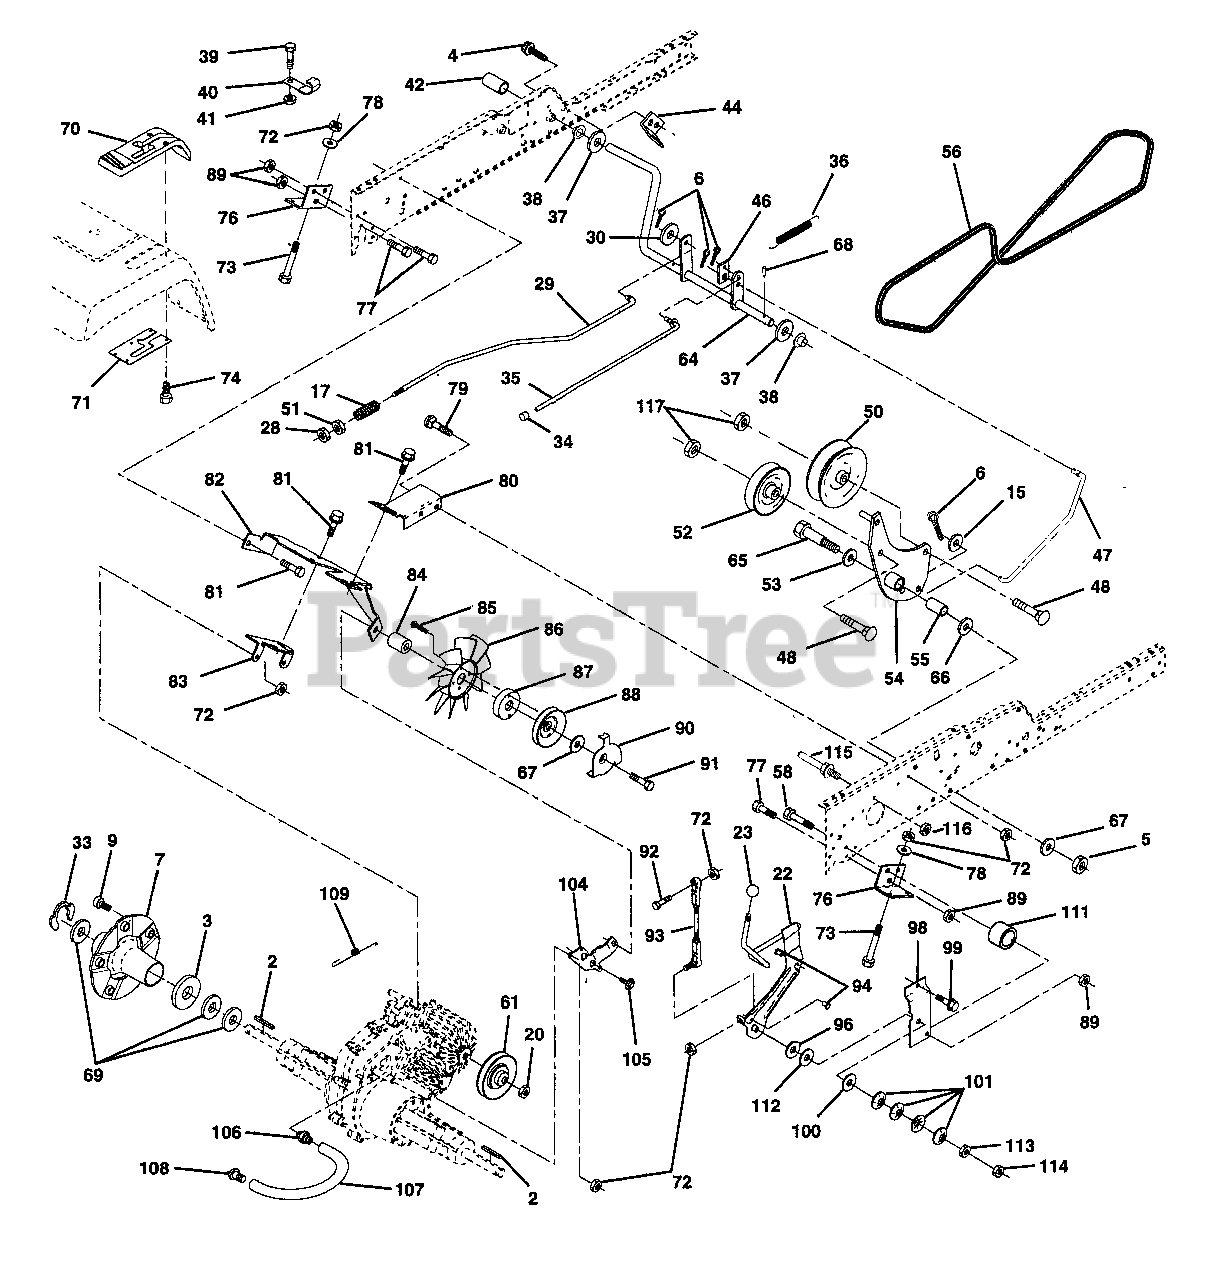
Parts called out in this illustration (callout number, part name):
2	Key 1 /4 x 2.5
3	Washer Thrust Axle Harden
4	Screw Thdrol 5/16-18 x 1/2
5	Nut Crownlock 3/8-16
6	Pin Cotter 1/8 x 3/4
7	Wheel Hub Asm.
15	Washer 13/32 x 13/16 x 16 Ga.
17	Spring Rod Brake
20	Nut Hex Jam Toplock 1/2-20
22	Shaft Arm Asm
28	Nut, Hex Jam 3/8-16
30	Washer 13/32 x 1 x 16Ga
34	Cap Plunger
35	Rod Parking Brake
36	Spring Drive Ground
37	Washer 25/32 x 1-1/4 x 16 Ga.
39	Screw Fin #10-24 x 1
40	Actuator Interlock Switch
41	Nut Lock #10-24
42	Cover Pedal
44	Bracket Interlock
46	Retainer Spring
47	Clutch Rod
48	Bolt Carriage 3/8-16 x 1-1/2 Gr. 5
50	Pulley Idler Flat
51	Nut Lock Hex 3/8-16
52	Pulley Idler Grooved
53	Washer Hartdened
54	Clutch Arm Asm
55	Bearing, Idler
58	Bolt Fin Hex 7/16-14 x 1-1/2
61	Pullery Transaxle
64	Shaft Asm Brake Parking Clutch
65	Bolt Shoulder
66	Washer Hardened
67	Washer 13/32 x 13/16 x 12 Ga
70	Console Hydro Fender
71	Plate Console Shift
72	Locknut Hex W/Washer Insert
73	Bolt Fin Hex 5/16-18 x 3
74	Screw, Hex Wsh Hi-Lo 1/4-1 /2
76	Bracket Transaxle
77	Bolt Fin Hex 7/16-14 x 1
78	Washer 11/32 x 3/4 x 12 Ga.
79	Bolt Carriage 5/16-18 x 5/8
80	Bracket Torque RH
81	Screw Thdrol 3/8-16 x 3/4
82	Bracket Mount Torque/Fan
83	Strap Torque Mid
85	Screw #10-24 x 1-1/4
86	Fan 7" Hydro
87	Adapter Fan
88	Pulley Idler
89	Nut, Crownlock 7/16-14
90	Keeper Belt
91	Screw Thdrol 3/8-16 x 2-3/4
92	Bolt Fin Hex 5/16-18 x 1.75
93	Link Shift Asm
94	Fastner Christmas Tree
96	Washer Nickel Plated
98	Bracket Shift
99	Screw Thdrol 3/8-16 x 1-1/2
100	Washer Compression
101	Washer Bellville
104	Bracket Idler
105	Screw Tap 1 /4-20 x 1 /2
106	O-Ring Asm. Hydra Gear
107	Line Fuel Hydro
108	Cap Vent
109	Spring Return Brake
111	Spacer Shift Lever VGTH
112	Washer Nylon High Temp
113	Nut Hex ASF 7/16-14 Unc
114	Nut Crownlock 7/16-14 Unc
115	Keeper Belt Gnd Dr.
116	Nut Lock Hex Flange 5/16-18
117	Nut Lock Fig; 3/8-16 Unc
